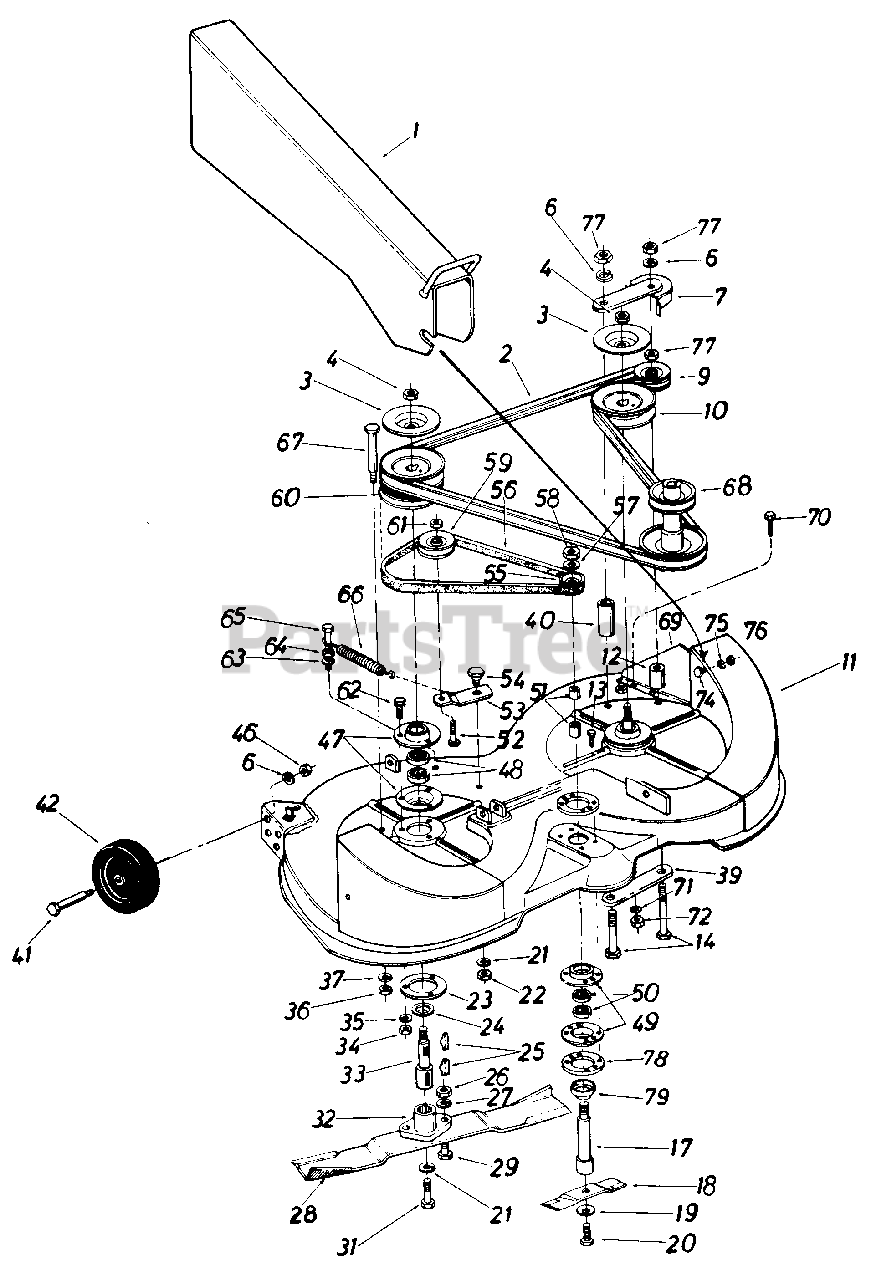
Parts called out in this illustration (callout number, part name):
1	Chute Extension Ass'y.
2	"V"-Belt
3	Brake Disc
4	Hex Cent. L-Nut 5/8-11 Thd.
6	L-Wash. 3/8" I.D.
7	Idler Pulley Belt Guard Ass'y.
9	5/8-V Belt Idler 3.50" O.D.
10	5/8-V Pulley .628" I.D. x 5.25" O.D.
11	40" Rear Discharge Deck
12	Spacer .40" I.D. x 1.25" O.D. x 1.59" Lg.
13	Hex B-Tap Scr. 1/4" X 1.0"
14	Hex Bolt 3/8-24 x 3.75" Lg.
17	Blade Spindle
18	6.50" Blade
19	Bell-Wash. .40" I.D. x .88" O.D.
20	Hex Bolt 3/8-24 x .87" Lg.
21	L-Wash. 3/8" I.D.
22	Hex L-Nut 3/8-16 Thd.
23	Plate Deck Reinforcement
24	Bearing Shield
25	#6 Hi-Pro Key 5/32 x 5/8" Dia.
26	Hex Nut 5/16-24 Thd.
27	L-Wash. 5/16" I.D.
28	20" High Lift Blade R.H.
29	Hex Bolt 5/16-24 x 1.00" Lg. (Grade 5)
31	Hex Bolt 3/8-24 x 1.50" Lg. (Grade 5)
32	Blade Adapter Kit
33	Blade Spindle
34	Hex Nut 5/16-18 Thd.
35	L-Wash. 5/16" I.D.
36	Hex L-Nut 3/8-16 Thd.
37	L-Wash. 3/8" I.D.
39	Reinforcement Plate
40	Spacer 3/8" I.D. x 50" O.D. x 2.72
41	Shld. Bolt .498" Dia. x 1.53"Lg.
42	Cutting Deck Wheel
46	Hex Jam Nut 3/8-16 Thd.
47	Bearing Housing
48	Ball Bearing .787" I.D. x 1.85" O.D.
49	Bearing Housing
50	Ball Bearing .63" I.D. x 1.38" O.D.
51	Spacer .63" I.D. x .88" O.D. x.57" Lg.
52	Hex Bolt 3/8-16 x 1.25" Lg.
53	Idler Bracket
54	Shld. Bolt .625" Dia. x .170"Lg.
55	3/8" V-Pulley .628" I.D. x 2.00" O.D.
56	"V"-Belt
57	Bell-Wash. .63" I.D. x 1.05" O.D.
58	Hex Jam Nut 5/8-11 Thd."
59	1/2" V-Belt Idler 2.625" O.D.
60	Double Pulley
61	Hex Top L-Jam Nut 3/8-16 Thd.
62	Hex Sems Bolt 5/16-18 x 1.00" Lg.
63	L-Wash. 1/4" I.D.
64	Hex Nut 1/4-20 Thd.
65	Hex Bolt 1/4-20 x 1.00" Lg.
66	Ext. Spring .50" O.D. x 3.97" Lg.
67	Shld. Bolt .498" Dia. x 2.63" Lg.
68	Two Step Engine Pulley
69	Inner Chute Extension L.H.
70	Hex Sems Scr. 1/4-28 x .62" Lg.
71	L-Wash. 1/4" I.D.
72	Hex Nut 1/4-28 Thd.
74	Shld. Scr. 500" Dia. x .218
75	L-Wash. 3/8" I.D.
76	Hex Jam Nut 3/8-16 Thd.
77	Hex Nut 3/8-24 Thd.
78	Reinforcement Plate
79	Bearing Shield
